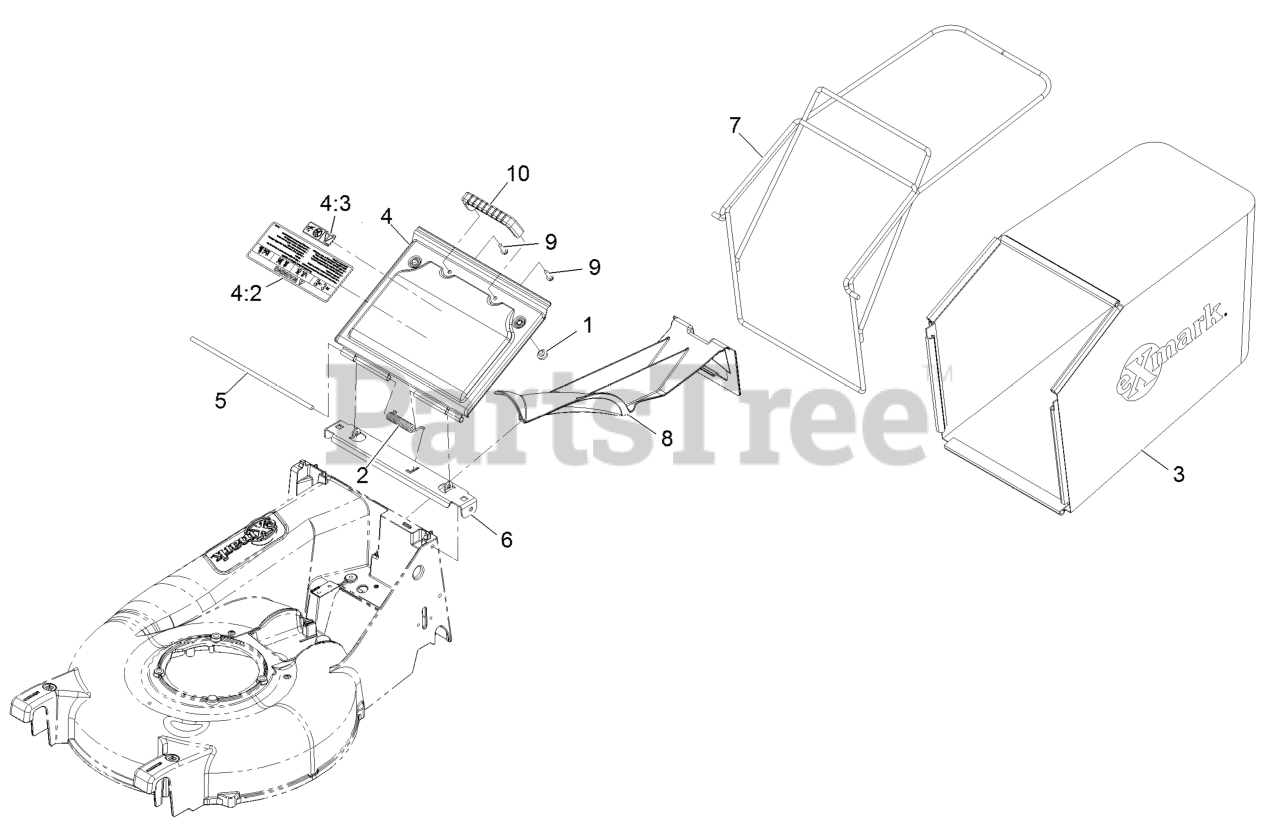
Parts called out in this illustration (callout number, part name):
2	SPRING-TORSION,COVER
3	BAG,GRASS P21
4	DOOR W/DECAL
4:2	DECAL-WARNING DOOR LG
4:3	DECAL-WARNING, BLOCK
5	ROD,DOOR PIVOT
6	BRACKET-DOOR P21
7	WLD,BAG FRAME
8	PLUG,MULCH
9	SCREW-HWH
10	HANDLE-DOOR
